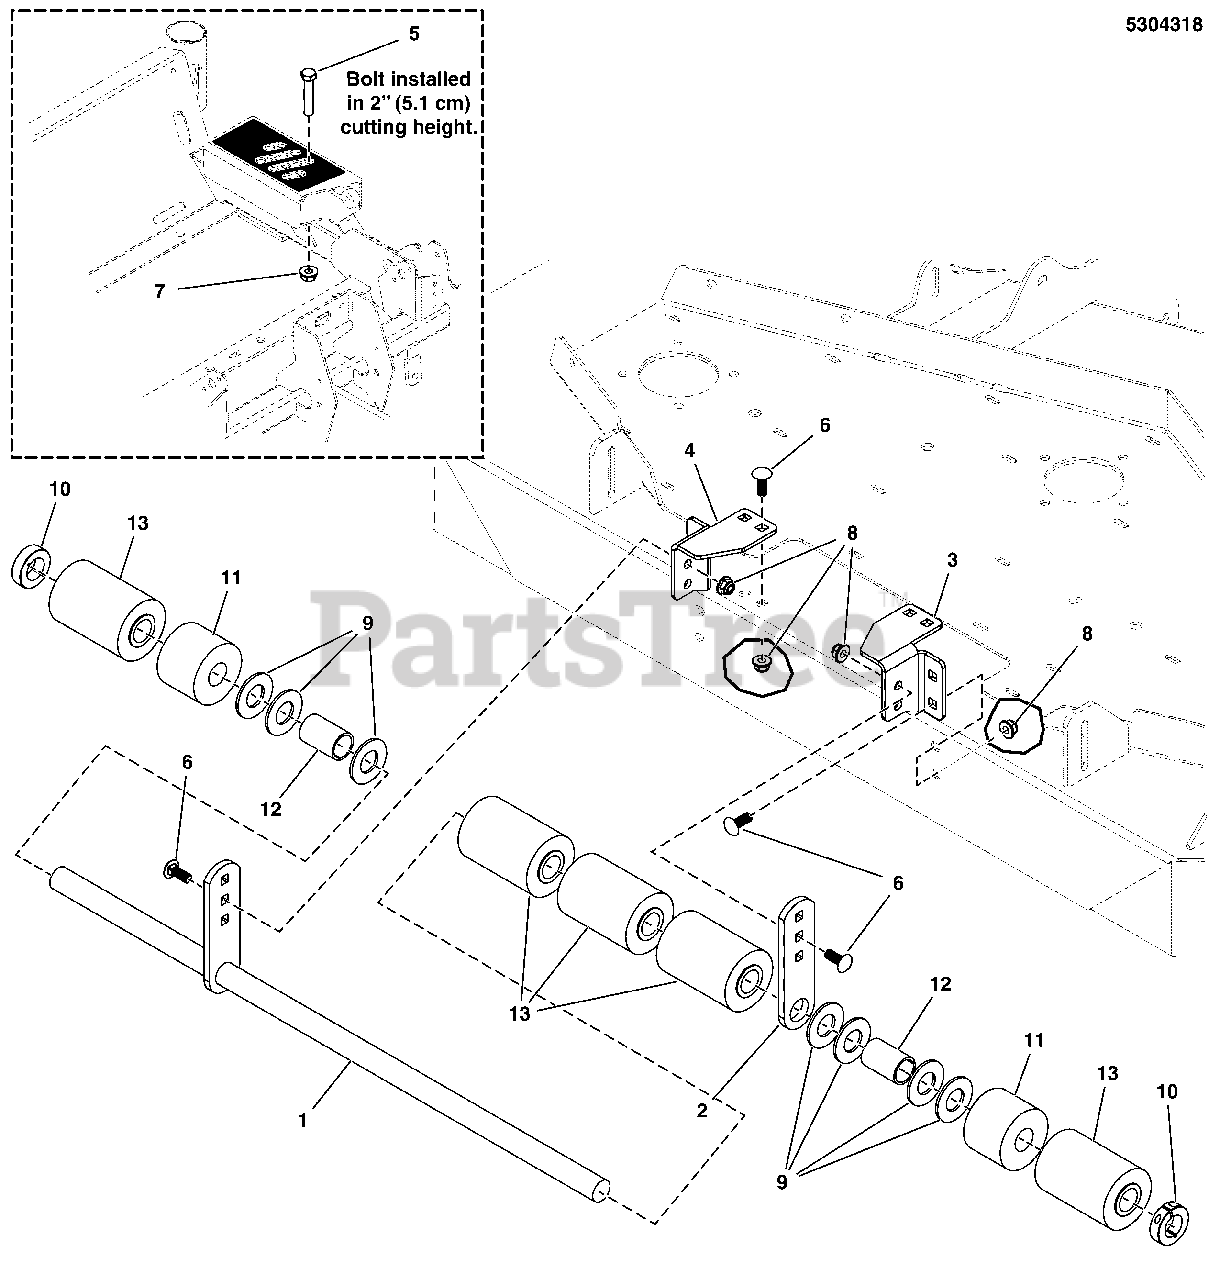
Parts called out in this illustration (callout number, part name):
1	WELD, ROLLER SHAFT, CONTENDER - BLK
2	PLATE, ROLLER ARM, CONTENDER - 61 - BLK
3	PLATE-MOUNT, RIGHT
4	MOUNT, LH, ROLLER, CONTENDER - 61 - BLK
5	BOLT, 1/2-13 X 2-1/2 GD5 CZ
6	BOLT,3/8-16X1.00,RD SH SQ NK,GR 5,ZC/CL
7	NUT, 1/2-13 HEX NYLON LOCK
8	NUT, 3/8-16 HEX NYLOCK FLANGE
9	WASHER-1.00 HYDRO CUT
10	COLLAR, 1 SPLIT
11	ROLLER-1.010ID 2
12	SPACER-1.02 IDX0.105WLX1.87 LG BLK
13	ROLLER W/BUSHINGS BLACK POLY
